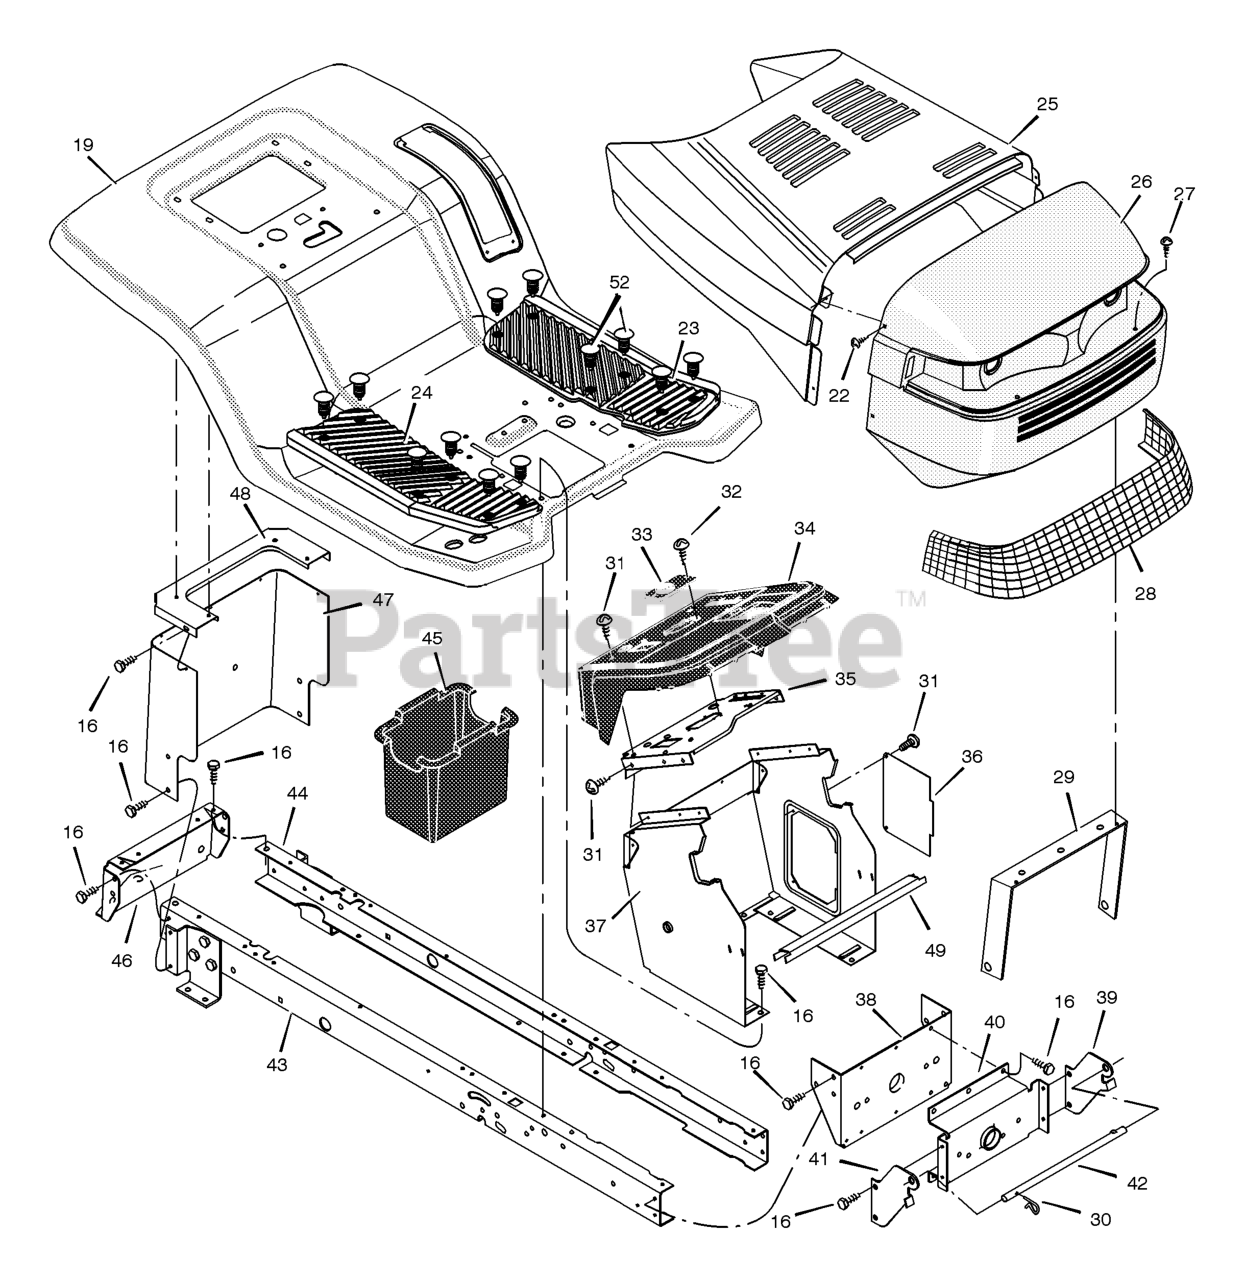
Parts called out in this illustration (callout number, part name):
19	Deck, Seat
23	Mat, Left
24	Mat, Right
25	Hood
26	Grille Assembly
29	Brace, Grille
30	Pin, Hair
31	Screw
33	Bearing, Steering
35	Plate, Dash
36	Panel, Access
37	Support, Dash
38	Bracket, Rear Hanger
39	Support, Left Grille
40	Axle, Hanger
41	Support, Right Grille
42	Rod, Pivot
43	Frame, Right
44	Frame, Left
45	Container, Battery
46	Plate, Hitch
47	Plate, Rear
48	Top, Rear Plate
52	Fastener
